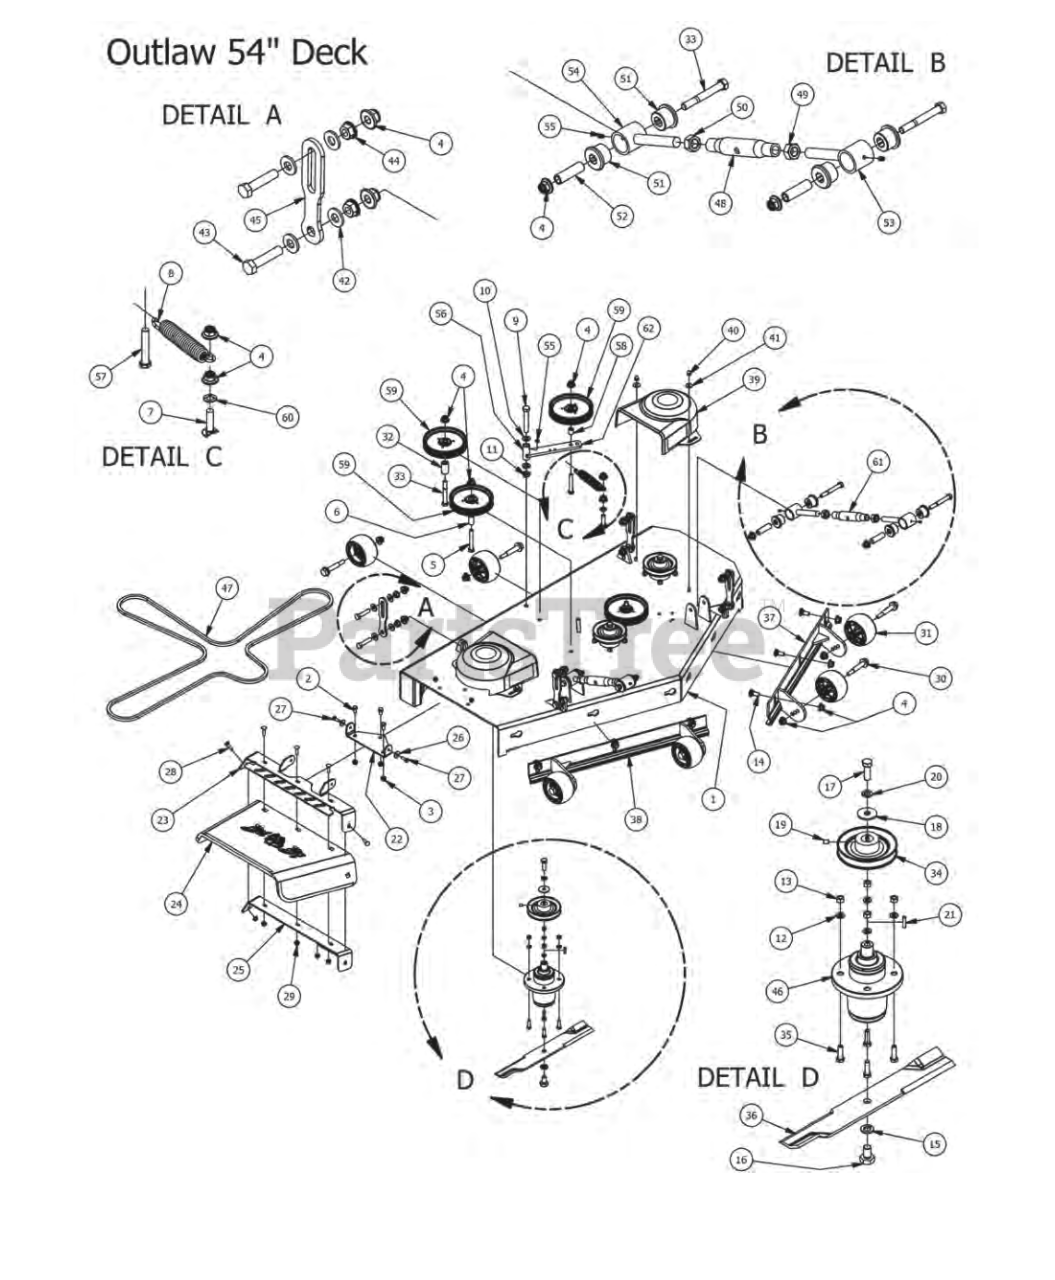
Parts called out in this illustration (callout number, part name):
1	2015 54" Deck
2	3/8" x 3/4" Hex Bolt
3	3/8" Flange Nut
4	1/2-13 Nylon Flange Nut-Orange
5	1/2 x 3 1/2 Flange Bolt Grade 8
6	502 ID X.75 OD X 1.500 Leng
7	1/2 x 2" Carriage Bolt
8	2015 Deck Idler Spring Outlaws
9	5/8" x 4" Hex Bolt
10	635 ID Plastic Washer
11	5/8-11 Nylon Insert Jam Half Nut
12	3/8 Lockwasher Zinc
13	3/8-16 Hex Nuts Zinc
14	1/2" x 1 1/4 Carriage Bolt
15	5/8" Lock Washer
16	5/8" x 1 1/2" Gr8 Hex Bolt (Fine)
17	1/2"-20 x 1 1/2-Grade 5 Fine Thread Bolt
18	1/2 Belleville Washer
19	5/16 Set Screw
20	1/2" Lock Washer
21	1/4" x 1" Key
22	Discharge Chute Hanger (deck mounted)
23	60" Discharge Chute Upper Hanger
24	Rubber Discharge Chute
25	60" Discharge Lower Bracket
26	360 ID Plastic Washer
27	5/16" x 1" Bolt
28	5/16" x 1 1/4" Carriage Bolt
29	5/16" Flange Nut Zinc W/Senations
30	Deck Wheel Bolt
31	Anti-Scalp Rollers
32	13/4" Pulley Spacer
33	1/2" x 4" Bolt (Grade 8)
34	5" Deck Pulley
35	3/8" x 1 1/4" Hex Bolt
36	54" Deck Fusion Blade For Outlaw
37	54 Deck Adustable Front (Left)
38	54 Deck Adustable Front (Right)
39	Pulley Cover
40	Acorn nut-pulley Cover
41	360 ID Plastic Washer-Black
42	505 Nylon Spacer
43	1/2-13X 2-1/4 GR Hex Bolts
44	1/2" Flange Nut
45	Deck Hanging Tab
46	OUTLAW SPINDLE ASSEMBLY
47	60" ZT Deck Belt
49	3/4-10 Left-Handed Hex Nuts Zinc
50	3/4-10 Hex Nuts Zinc
53	Tum Left-Handed
54	Right-Handed End
55	1/4" Press in Grease Fitting
56	Deck Idler
57	1/2-13 x GR 5 Hex Bolt Zinc
58	3/4 OD x 1/2 1D x 3/4 Length
59	5-3/4 Idler Pulley
60	517 Square Hole Round Washer
61	Turnbuckle Assembly
62	Deck Idler Assembly Includes parts: 4,10,59,60,61
